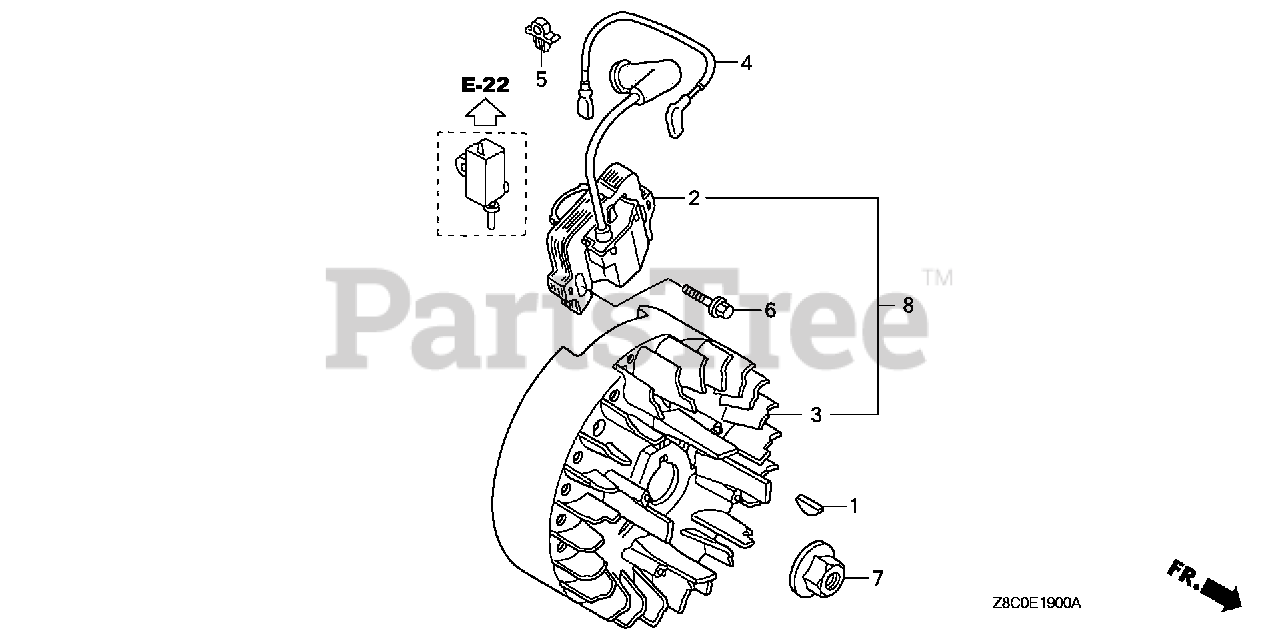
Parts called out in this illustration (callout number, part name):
1	KEY, SPECIAL WOODRUFF (25X18)
2	COIL ASSY., IGNITION (USE FOR F/W OF TEC) (TEC) Use up to Engine SN 3747197.
2	COIL ASSY., IGNITION (PHELON) (USE FOR F/W OF PHELON)
2	COIL ASSY., IGNITION (PHELON)
3	FLYWHEEL COMP. (PHELON) (USE FOR IGN. COIL OF PHELON) (USE FOR PHELON IGNITION COIL)
3	FLYWHEEL COMP.(TEC) (USE FOR IGN. COIL OF TEC)
4	WIRE, STOP SWITCH
5	HOLDER, STOP SWITCH WIRE Use up to Engine SN 2056819.
5	HOLDER, WIRE (FASTEX)
6	BOLT, FLANGE (6X20) (CT200)
7	NUT, FLANGE (14MM)
8	FLYWHEEL KIT (SEL)
